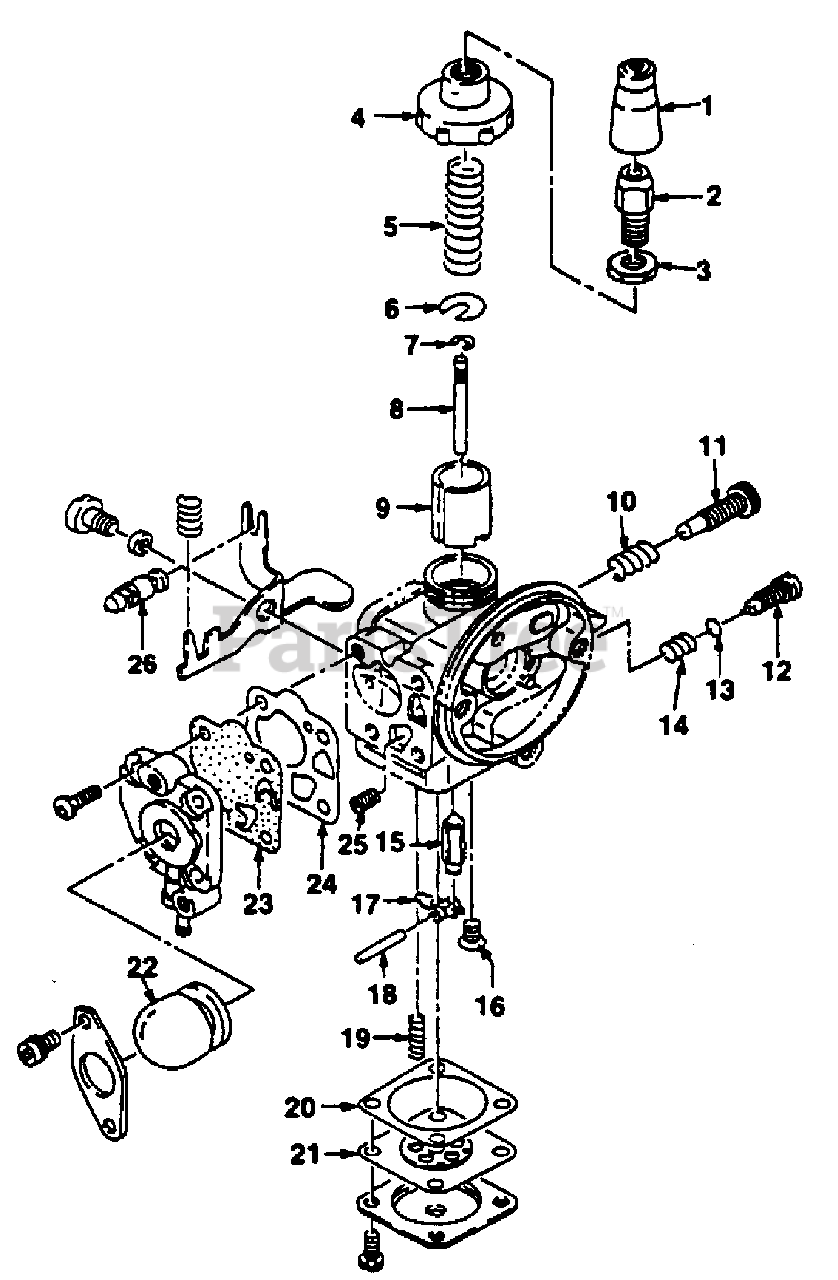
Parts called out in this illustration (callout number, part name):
2	CABLE- Adj.
3	NUT- Lock
4	CAP- Carb. body
5	Needle Jet Kit
6	Needle Jet Kit
7	Needle Jet Kit
8	Needle Jet Kit
9	Repair Kit
10	Repair Kit
11	Repair Kit
12	Repair Kit
13	Repair Kit
14	Repair Kit
15	Repair Kit
16	Repair Kit
17	Repair Kit
18	Repair Kit
19	Repair Kit
20	Repair Kit
21	Repair Kit
22	PRIMER BULB
23	Repair Kit
24	Repair Kit
25	Repair Kit
26	Repair Kit
